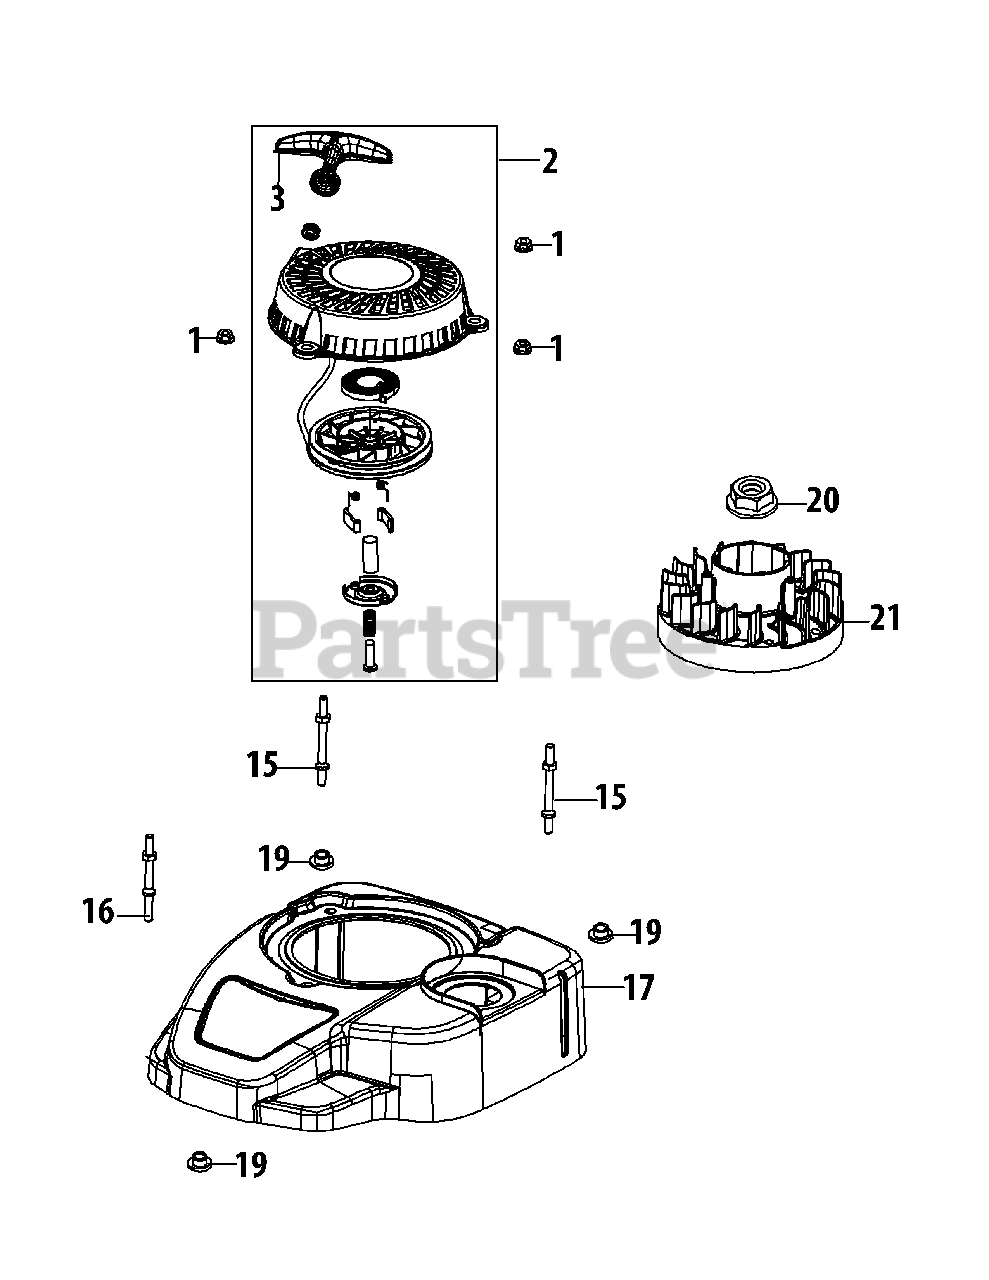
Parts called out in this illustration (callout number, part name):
1	Nut M6X10Mm Starter/Carb/Muff
2	Starter Recoil Assembly
3	Starter Handle
15	Starter/Shroud Rear Stud M6×75
16	Starter/Shroud Front Stud M6×73
17	Engine Shroud Assembly
19	Engine Shroud Spacer
20	Flywheel Nut M14
21	Flywheel
